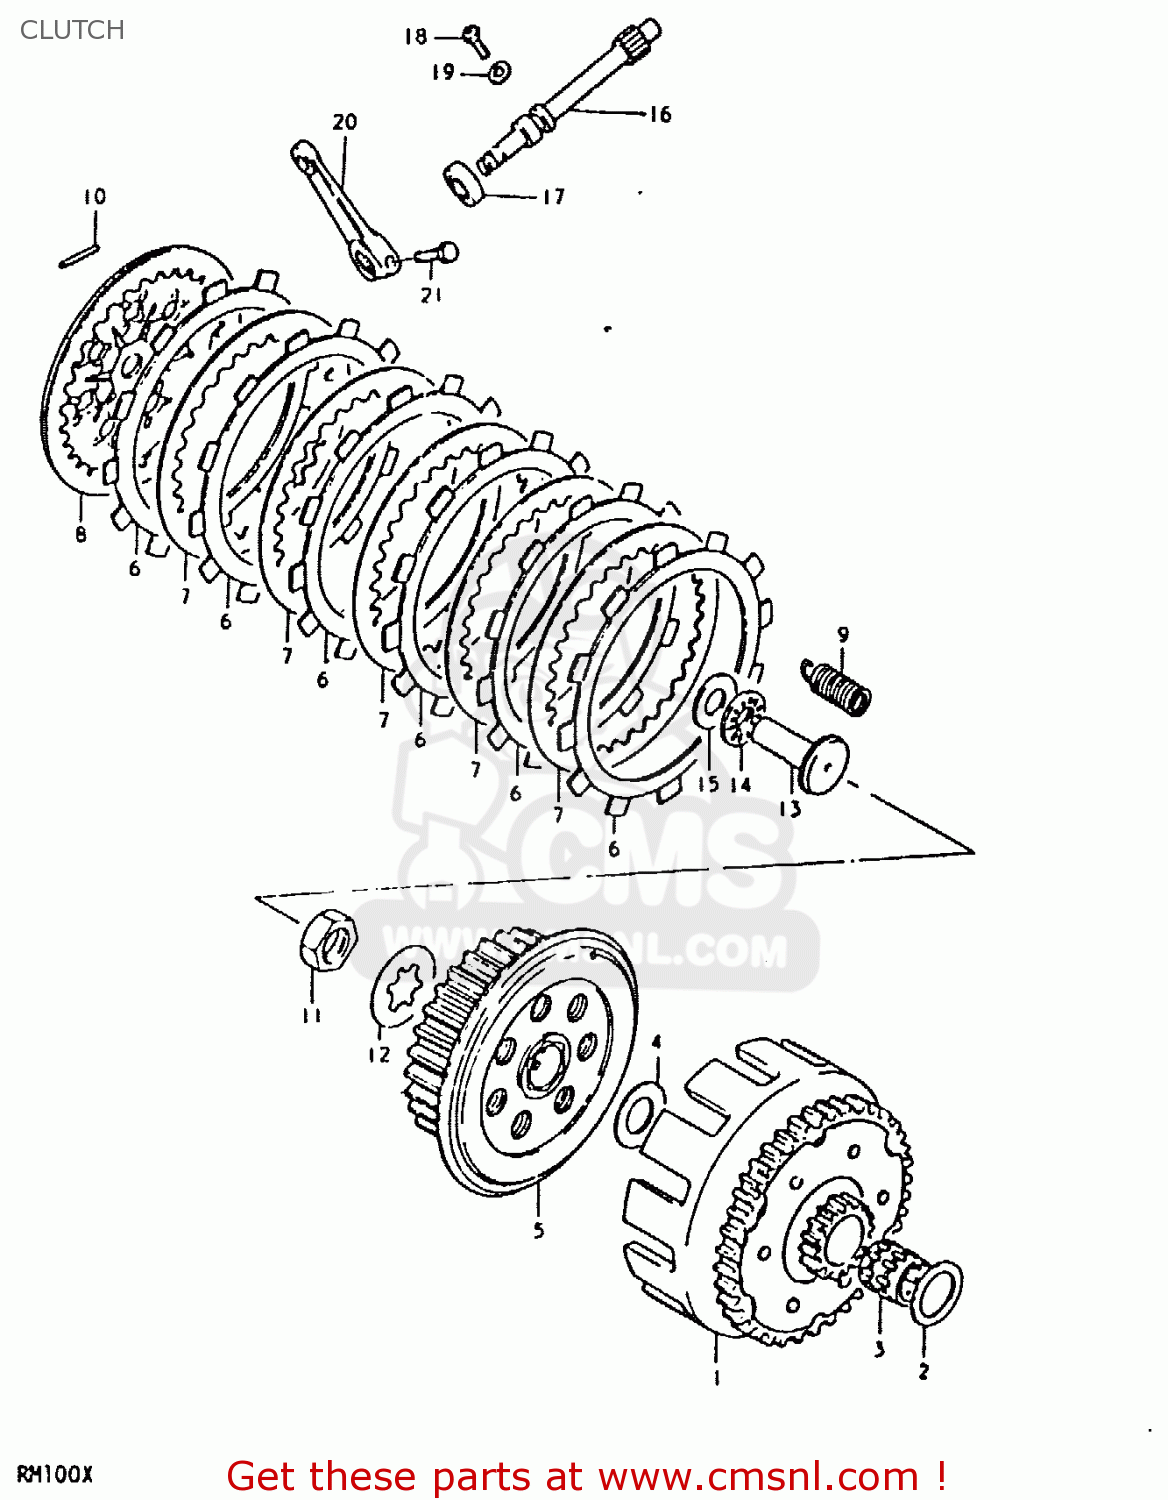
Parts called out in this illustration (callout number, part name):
1	GEAR ASSEMBLY,PRIMARY DRIVE
2	WASHER
3	BEARING(20X25X26)
4	WASHER
5	HUB,CLUTCH SLEEVE
6	PLATE,CLUTCH DRIVE
7	PLATE,CLUTCH DRIVEN
8	PLATE,CLUTCH PRESSURE
9	SPRING
10	PIN(2.5X19.8)
11	NUT
12	WASHER,LOCK
13	RACK,CLUTCH RELEASE
14	BEARING(10X22X2.8)
15	WASHER
16	PINION,CLUTCH RELEASE
17	SEAL,OIL (10X17X5)
18	BOLT(6X12)
19	WASHER
20	ARM,CLUTCH RELEASE
21	BOLT, UPPER
